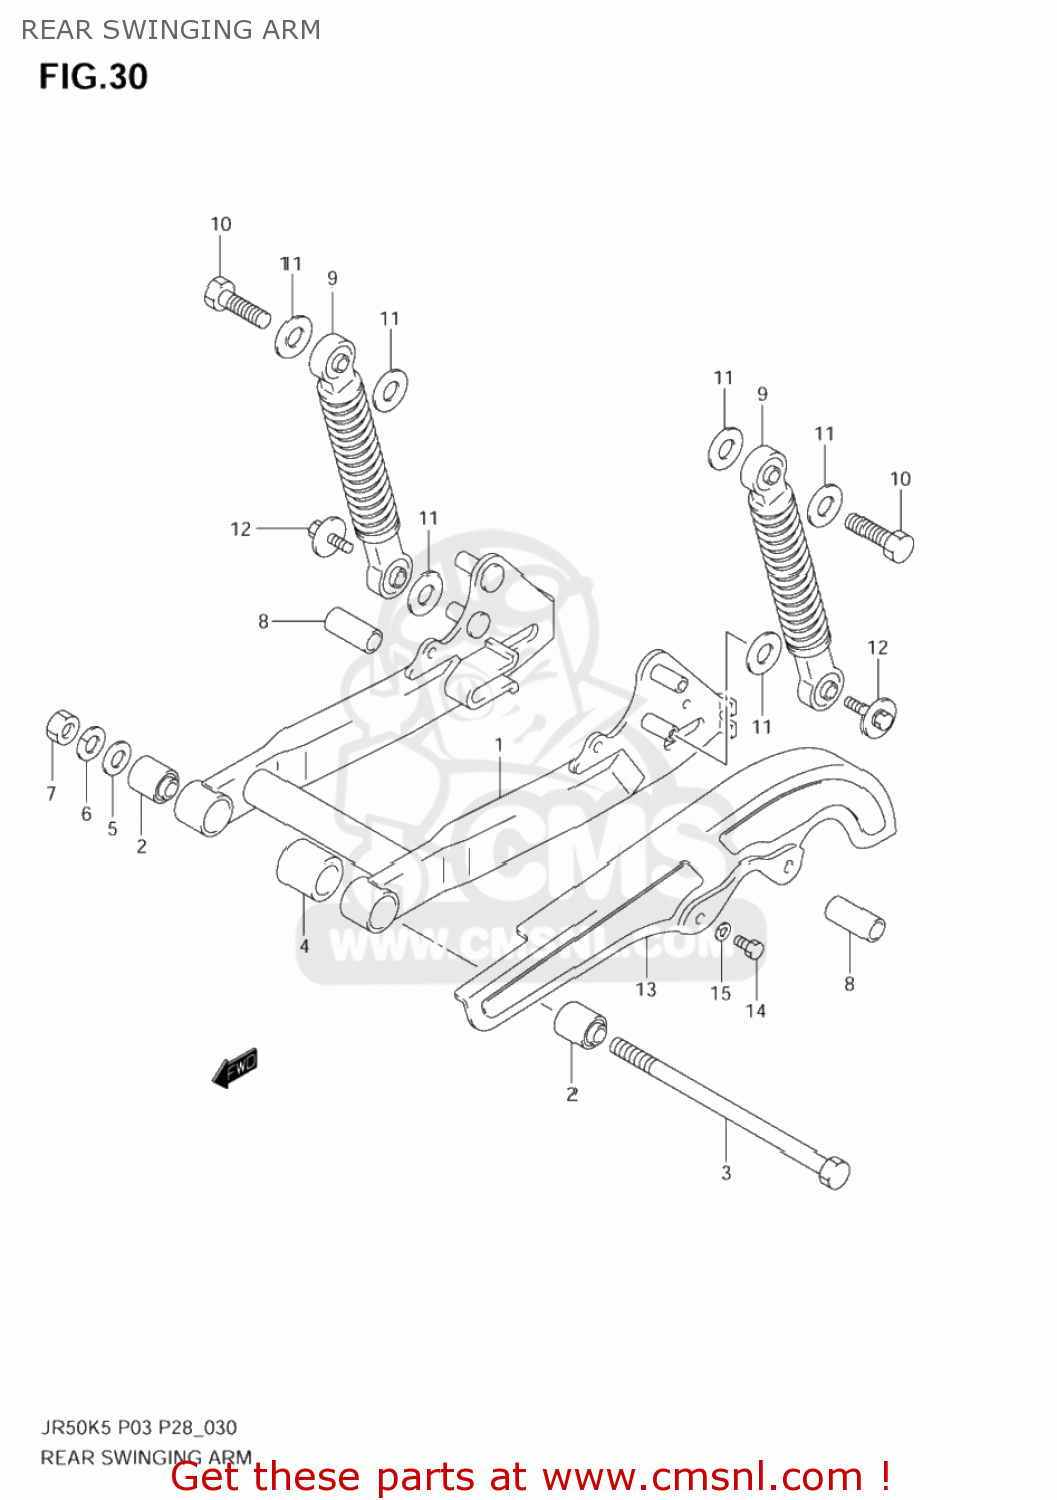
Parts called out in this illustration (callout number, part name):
1	SWINGINGARM ASSY,RR
2	BUSH
3	SHAFT,RR SWINGINGARM PIVOT
4	CUSHION,RR SWINGING ARM PIVOT
5	WASHER(10.5X22X1.6)
6	WASHER
7	NUT
8	CAP,RR SHOCK ABSORBER BOSS
9	ABSORBER ASSY,RR SHOCK
10	BOLT
11	WASHER(10.5X22X1.6)
12	BOLT(6X12)
13	CASE,CHAIN
14	BOLT
15	LOCK WASHER
